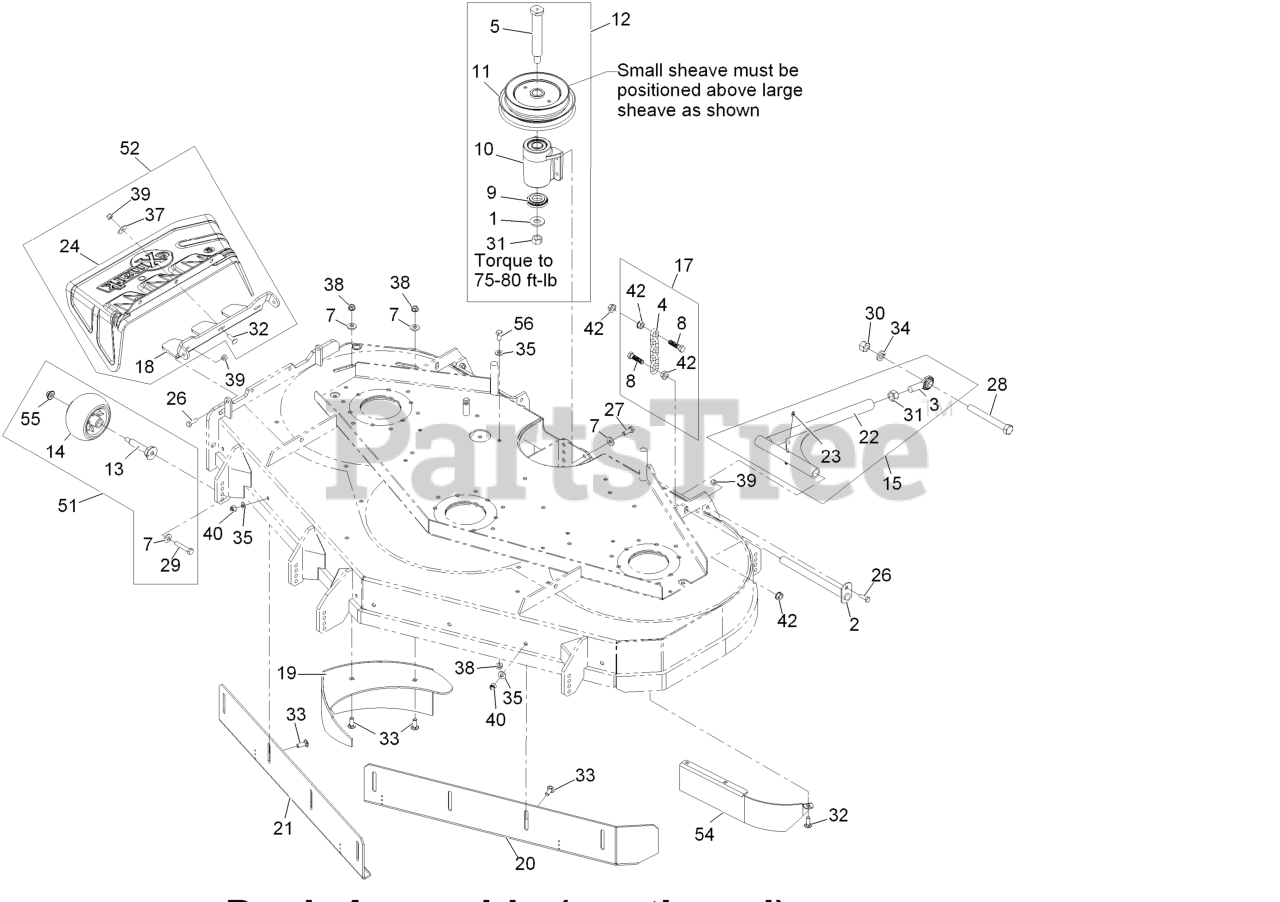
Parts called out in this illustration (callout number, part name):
1	WASHER-SPRING
2	PIN-STRUT
3	BALLJOINT-SPHERICAL
4	CHAIN-LIFT, DECK
5	JACKSHAFT
7	WASHER-BELLEVILLE
8	SCREW-HH
9	SPACER-GUARD, BOTTOM
10	KIT, JACKSHAFT ASSY
11	SHEAVE, JACKSHAFT DOUBLE
12	KIT,JACKSHAFT 60/72-3750
14	ROLLER-SCALP, ANTI
15	ASM,DECK STRUT XS 60
17	DECK CHAIN ASM
18	HINGE,DISCHARGE CHUTE
19	WLD,DOGLEG 605
20	WLD,BAFFLE FRT ADJ LH 605
21	WLD,BAFFLE FRT ADJ RH 605
22	STRUT-DECK
24	CHUTE,DISCHARGE LZ
26	SCREW-HH
27	SCREW-HH
28	SCREW-HH
29	SCREW-HH
30	NUT-HEX
31	NUT-HEX
32	SCREW-CARR
33	SCREW-CARR
34	WASHER-LOCK
35	WASHER-FLAT
37	WASHER-FLAT
38	NUT-HHF, WHIZ
39	NUT-LOCK, NI
40	NUT-LOCK, NI
52	ASM, DISCHARGE CHUTE
54	BAFFLE,SCROLL 605
55	Nut-Nyloc 3/8-16 Flg
56	SCREW-HH
